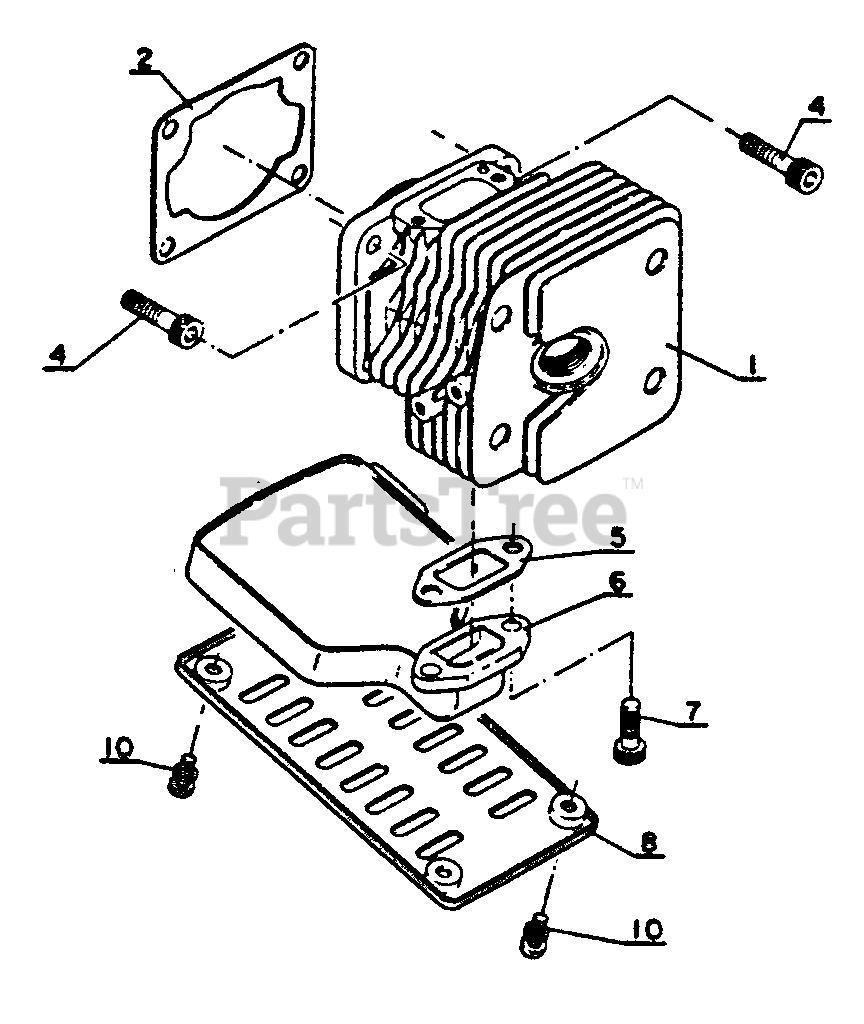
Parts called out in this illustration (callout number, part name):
1	CYLINDER
2	GASKET, CYLINDER
4	SCREW - 5X20
5	GASKET, EXHAUST
6	MUFFLER
7	SCREW - 5X15
8	COVER, MUFFLER
10	SCREW - 4X10
